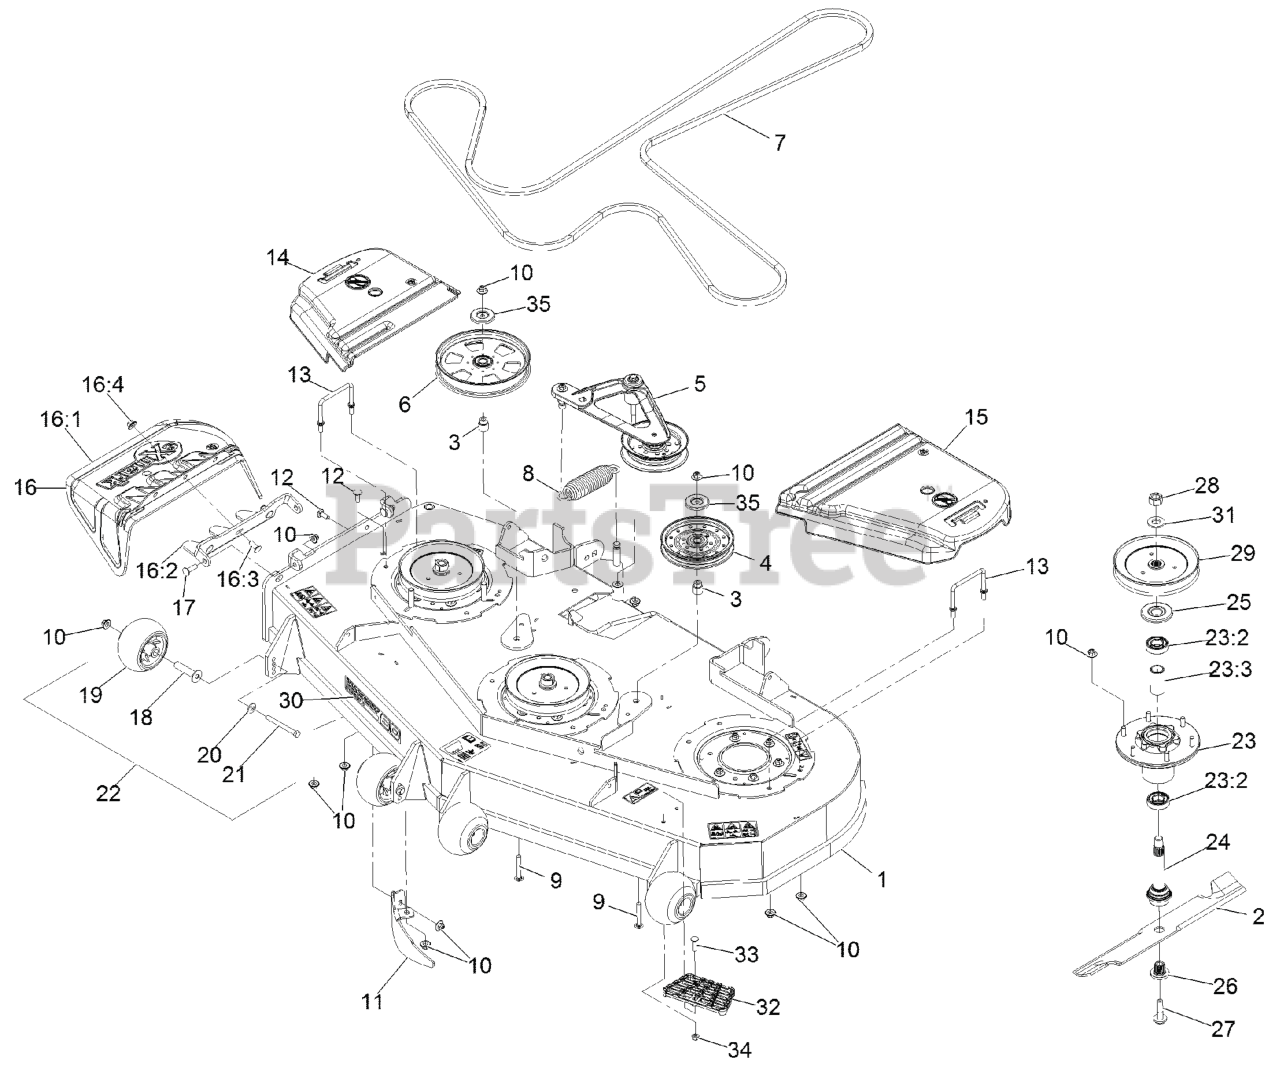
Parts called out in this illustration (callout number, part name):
1	DECK ASM,W/DECALS 60
2	Blade-Extreme 2, 20.50"
3	BUSHING-IDLER
4	IDLER-PULLEY
5	DECK IDLER ASM
6	PULLEY-IDLER, FLAT
8	SPRING-EXTENSION
9	SCREW-CARR
10	Nut-Nyloc 3/8-16 Flg
11	DOGLEG - LZ60
12	SCREW-CARR
13	WIREFORM-COVER
14	COVER-BELT, RH
15	COVER-BELT, LH
16	ASM,DISCHARGE CHUTE
16:1	CHUTE,DISCHARGE
16:2	BRACKET,DISCHARGE CHUTE
16:3	SCREW-CARR
16:4	Nut-Nyloc 3/8-16 Flg
17	Bolt-Carriage 3/8-16 X 1 1/4
18	AXLE, ROLLER
19	ROLLER-SCALP, ANTI
20	WASHER-BELLEVILLE
21	SCREW-HH 3/8-16 X 3 3/4 GR 8
22	KIT, ANTI-SCALP ROLLER
23	ASM-CUTTER HSG WITH BEARINGS
23:2	BEARING-BALL
23:3	SPACER-BEARING
24	ASM-SPINDLE AND SEAL
25	GUARD,BEARING TOP .989
26	BUSHING,SPLINED
27	SCREW,SEMS 1/2-20 X 2.19
28	NUT-HEX
29	SHEAVE,BLADE DRIVE 7.25
30	DECAL, 604
32	STEP-DECK
33	Bolt-Carriage 5/16-18 X 1 1/4
34	NUT-HF, NI
35	SHIELD-DUST
